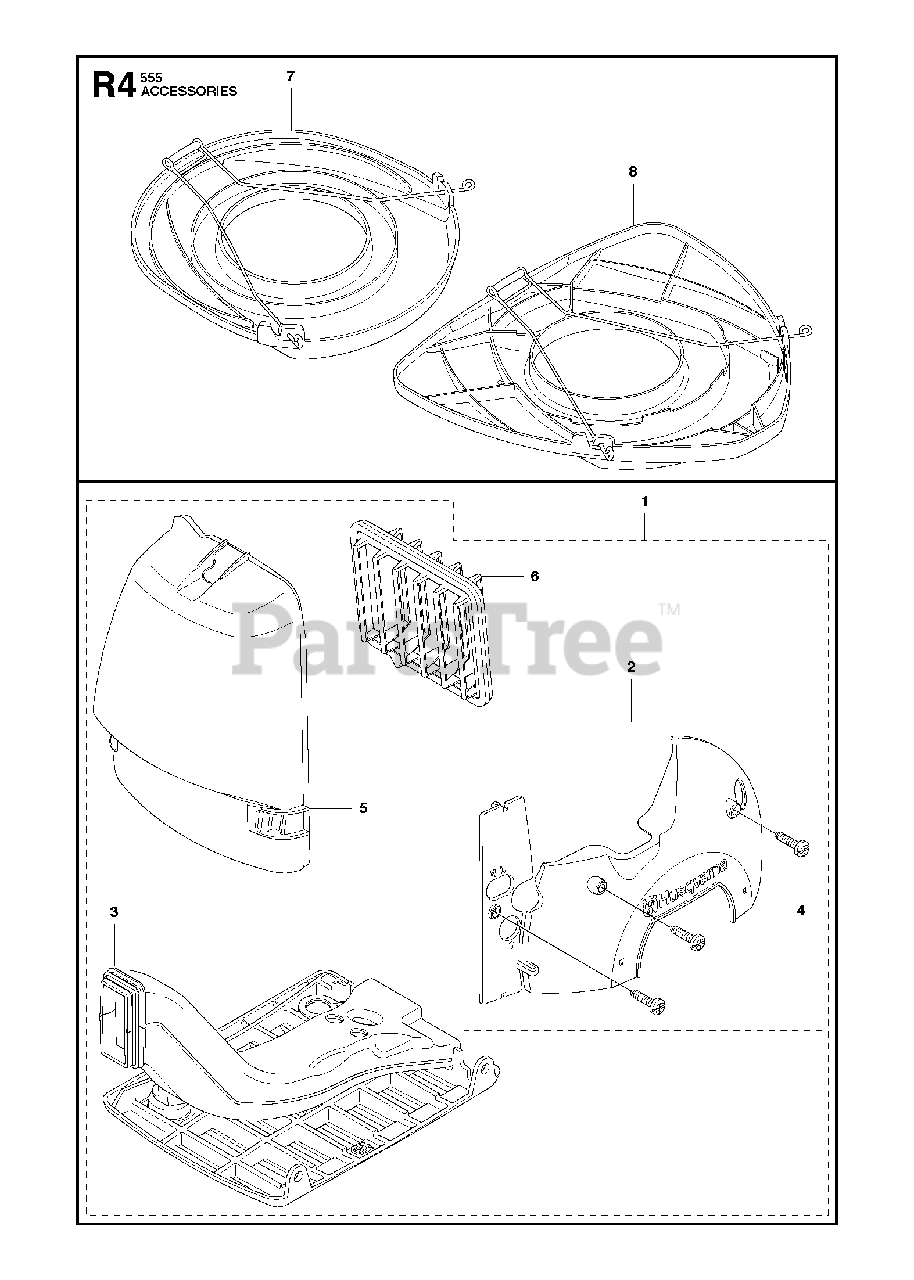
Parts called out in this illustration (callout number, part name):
1	WINTER KIT
2	WINTER COVER KPL VALID FROM RE
3	AIR DUCT
4	SCREW
5	COVER
6	FILTER
7	BLADE GUARD TRANSPORT
8	TRANSPORT GUARD
